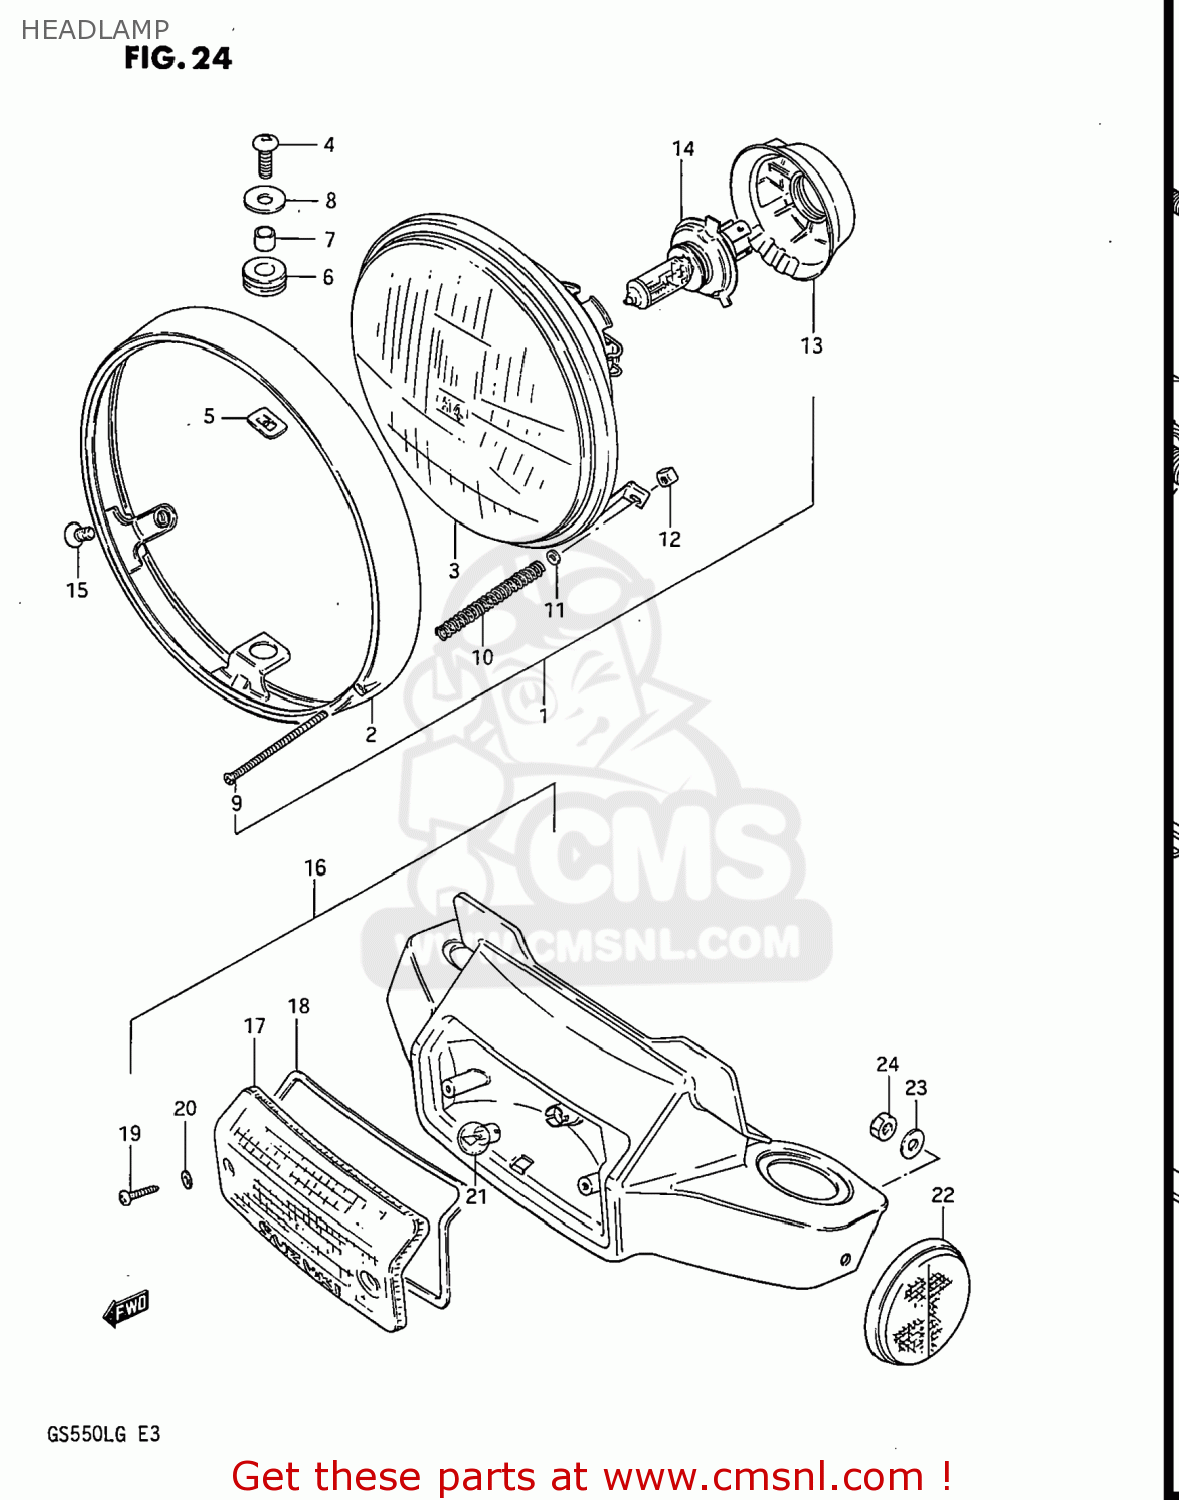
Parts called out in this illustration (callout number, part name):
1	HEADLAMP ASSY
2	RIM,HEAD LAMP
3	LAMP UNIT
4	SCREW(5X14)
5	NUT
6	CUSHION
7	SPACER
8	WASHER
9	SCREW,HEADLAMP ADJUST
10	SPRING,HEADLAMP ADJUST
11	WASHER
12	NUT
13	COVER,SOCKET
14	BULB(12V60/55W,H4)
15	SCREW(5X12)
16	LAMP ASSEMBLY,FRONT POSITION
17	LENS,POSITION LAMP
18	GASKET,POSITION LAMP
19	SCREW,POSITION LENS
20	GASKET (NAS)
21	BULB 12V 2CP
22	REFLEX REFLECTOR ASSEMBLY
23	WASHER
24	NUT
